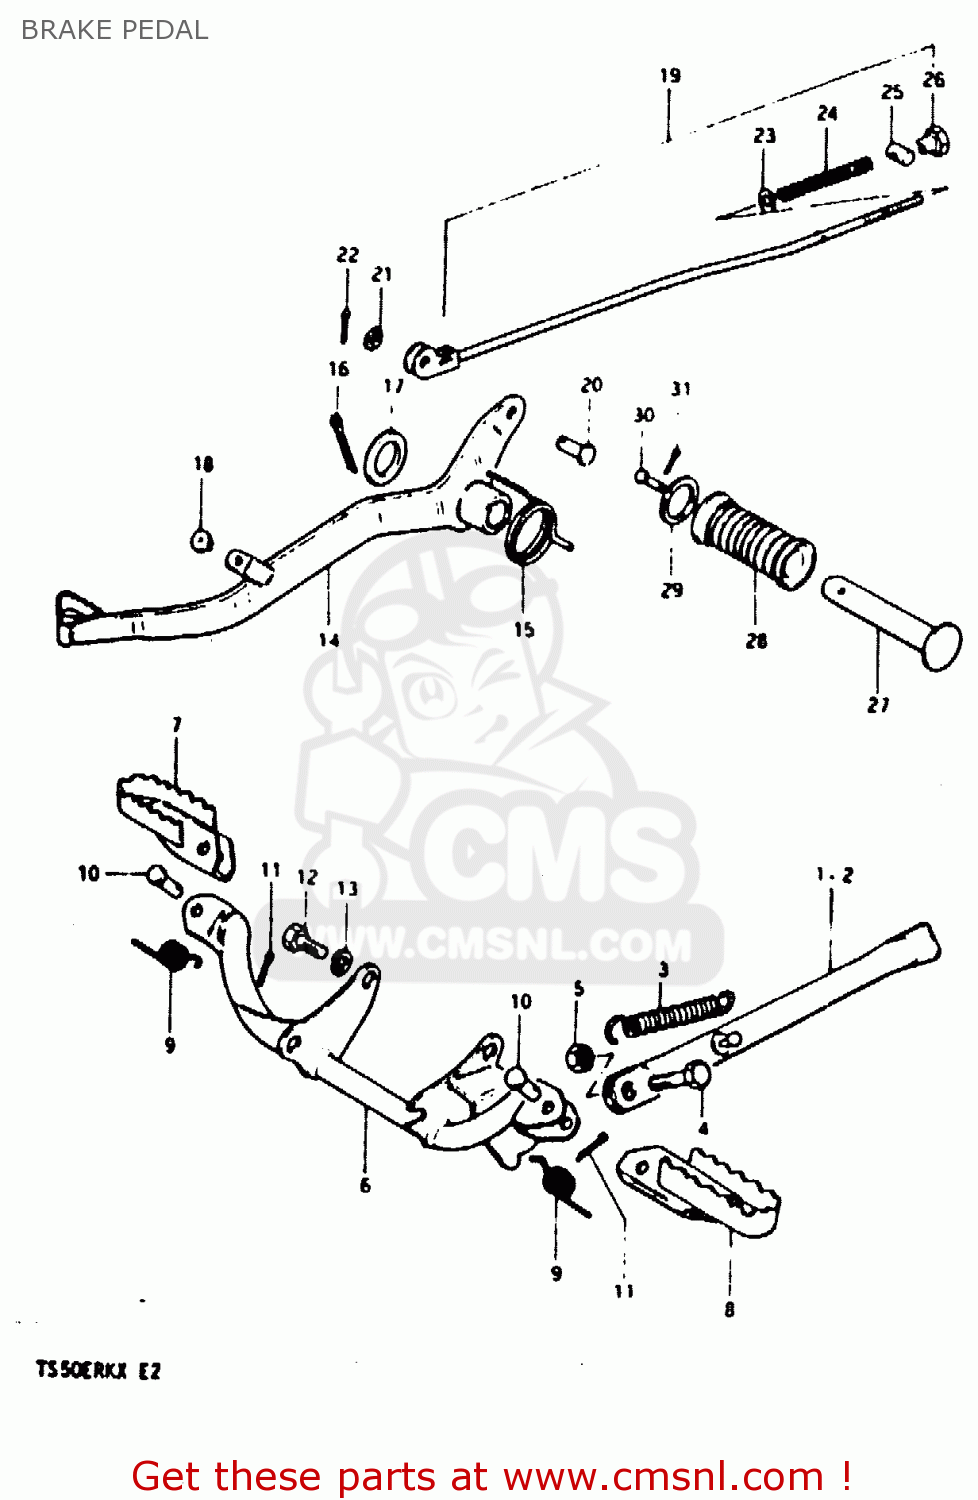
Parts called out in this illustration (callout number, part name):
1	STAND,SIDE
3	SPRING
4	BOLT
5	NUT
6	BAR, FRONT FOOTREST
7	FOOTREST,FRONT,RIGHT
8	FOOTREST
9	SPRING
10	PIN
11	PIN 20X20
12	BOLT
13	LOCK WASHER
14	PEDAL, BRAKE
15	SPRING
16	COTTER PIN
17	WASHER(15.5X26X2.3)
18	STOPPER,BRAKE PEDAL
19	ROD ASSEMBLY,REAR BRAKE
20	PIN(L:13.5)
21	WASHER
22	PIN 20X20
23	WASHER
24	SPRING
25	PIN(11X18)
26	NUT
27	BAR,FOOTREST RUBBER
28	RUBBER,PILLION FOOTREST
29	WASHER (19.5X32X2)
30	PIN
31	PIN 20X20
